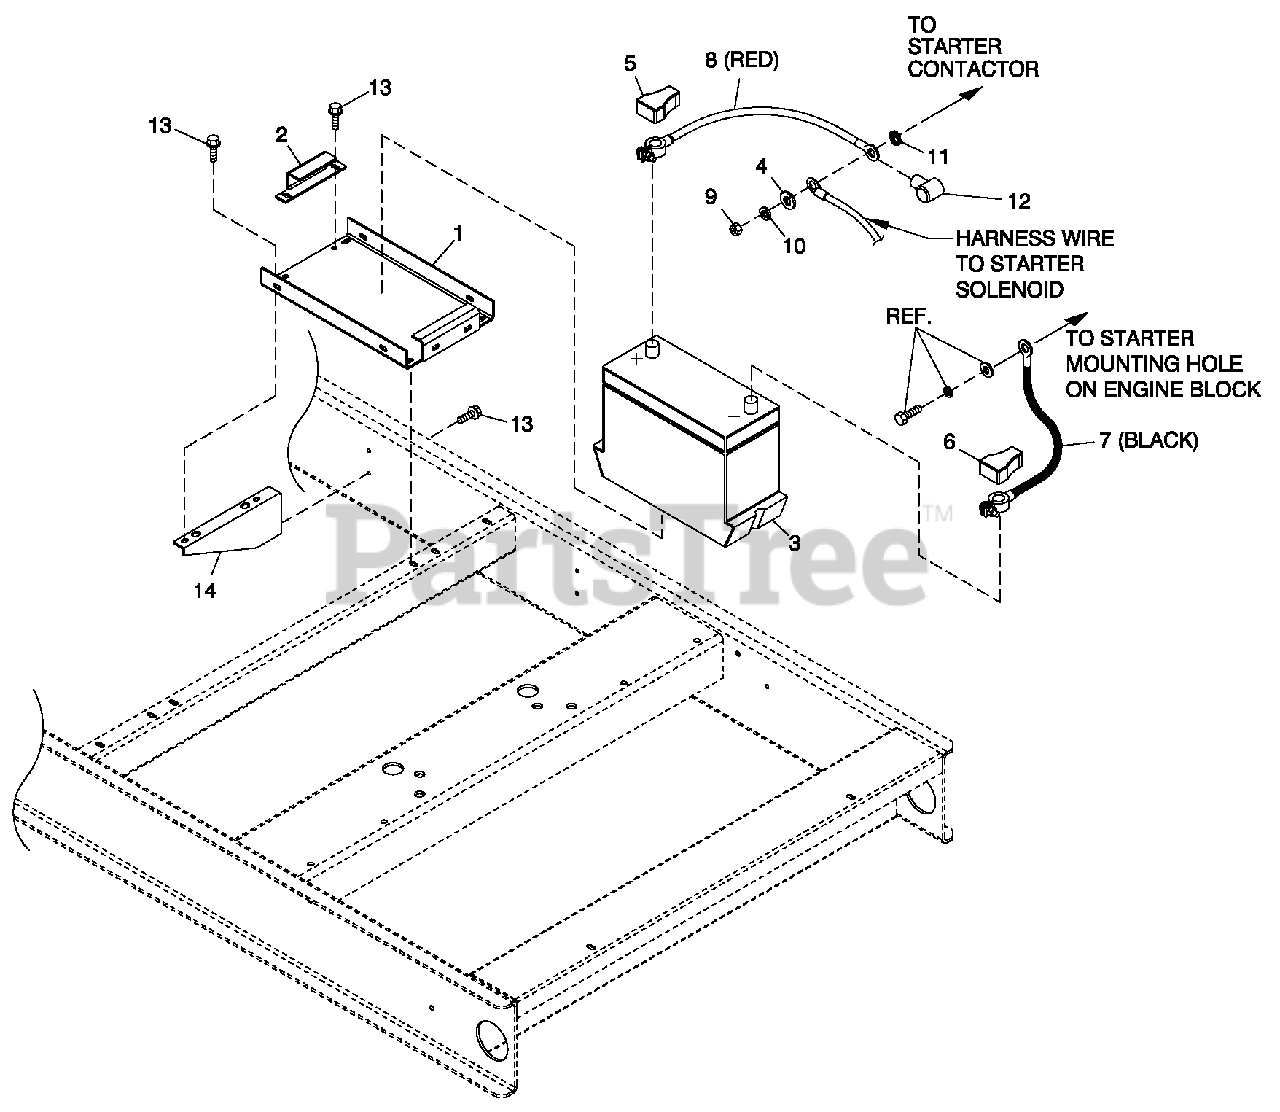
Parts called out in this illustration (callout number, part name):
1	TRAY BATTERY
2	STRAP BATTERY RETAINMENT
3	BATT 12VDC 24F 625
4	WASHER FLAT 3/8-M10 ZINC
5	BATT POST COVER RED +
6	BATT POST COVER BLK -
7	CABLE BATT BLK #1 X 18.00
8	CABLE BATT RED #1 X 28.00
9	NUT HEX M8-1.25 G8 YEL CHR
10	WASHER LOCK M8-5/16
11	WASHER SHAKEPROOF EXT 5/16 STL
12	BOOT BATTERY CABLE
13	SCREW THF M6-1X16 N WA Z/JS
14	SUPPORT BATTERY TRAY
